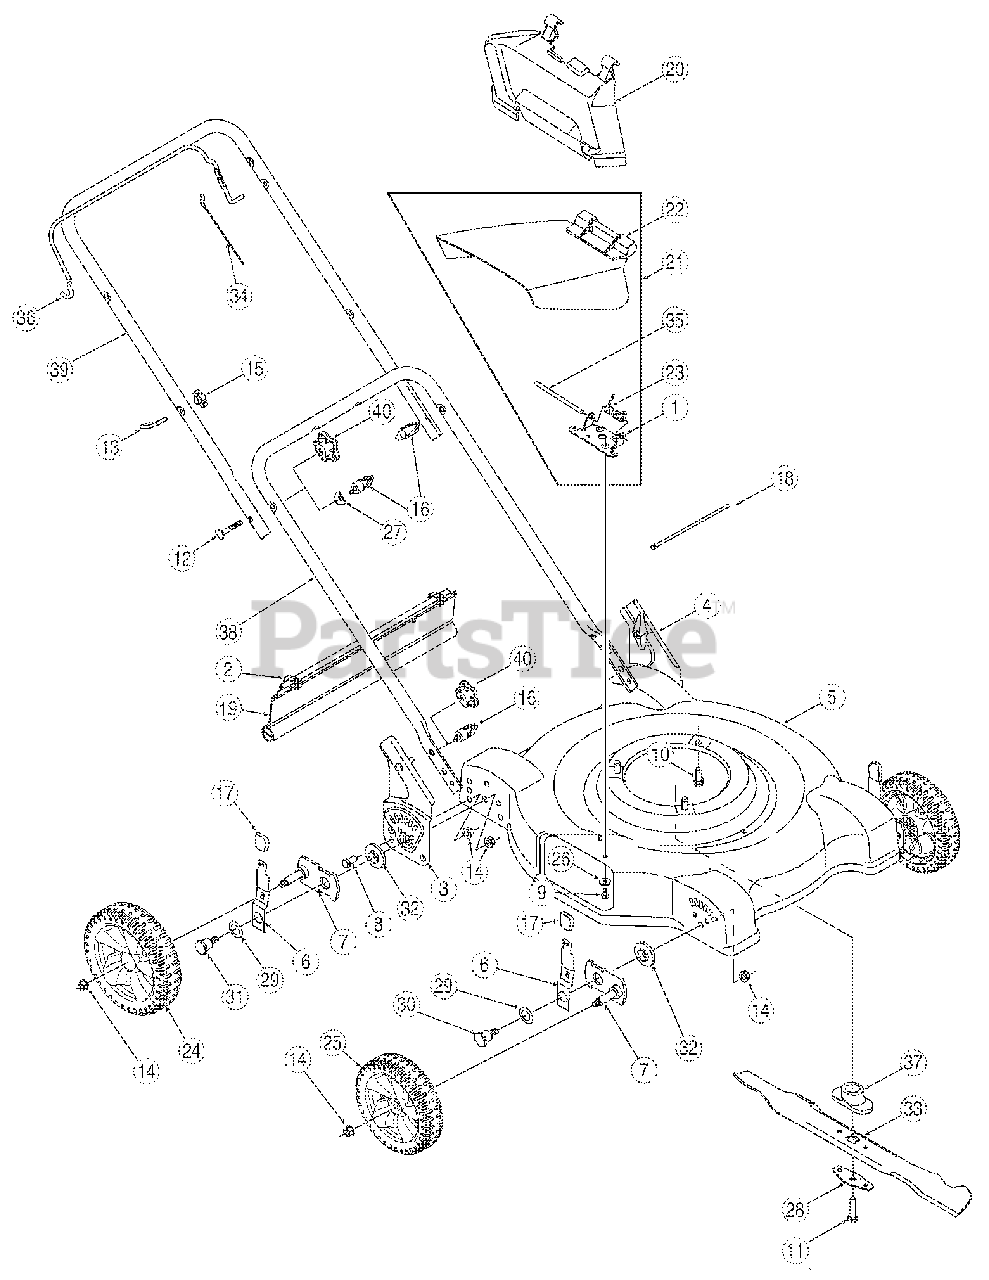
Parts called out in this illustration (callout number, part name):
1	Chute Hinge
2	Hinge Clip
6	Lever Ass'y
7	Pivot Arm
8	Hex Cap Screw 3/8-16 x .75
9	Hex Wash S-Tapp Scr 1/4-20X .50
10	Hex Wash HD Tap Scr 3/8-16 x .88
11	Hex Screw 3/8-24 x 1.5" Lg. (GR. 8)
12	Carriage Bolt 5/16-18 x 2.0
13	Rope Guide Bolt
14	Flanged Lock Nut 3/8-16
15	Knob - ERS Guide 1/4-20
16	Wing Nut
17	Knob
18	Cable Tie
19	Trail Shield
20	Mulching Baffle
21	Side Dis. Chute Ass’y
22	Chute Deflector
23	Torsion Spring
24	Rear Wheel 8 x 1.8
25	Front Wheel 7 x 1.8
26	Cup. Wash. .265 ID x .75 OD X .062
27	Saddle Wash. .320 ID x .937
28	Blade Bell Support
29	Cupped Washer.760 x 1.25
30	Shoulder Screw
31	Shoulder Screw
32	Height Adjuster Bearing
32	Blade 22"
33	Mulching Blade 22"
34	Blade Control Cable 48.25" Lg.
35	Hinge Pin
37	Blade Adapter 25 mm x 1.19
40	Knob - Star 16-18 5/16-18
